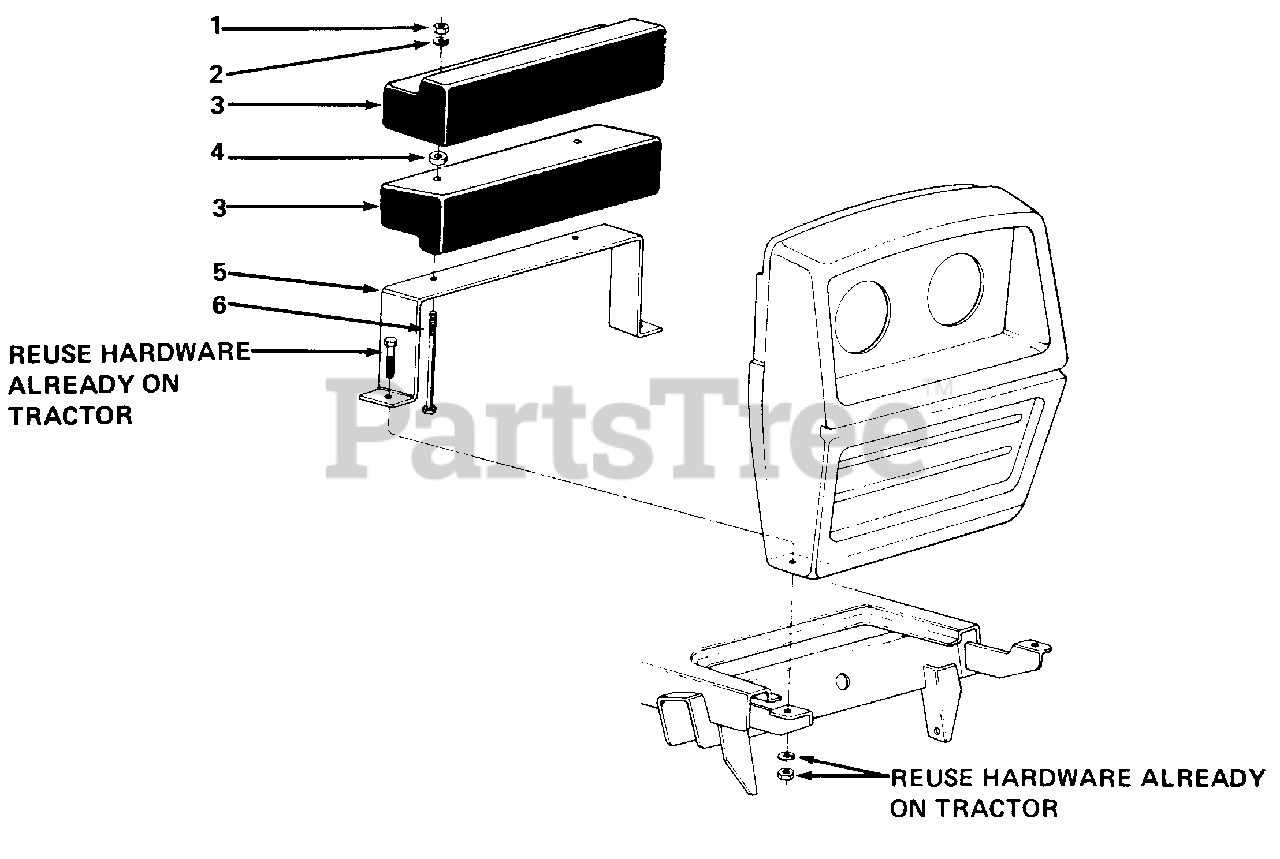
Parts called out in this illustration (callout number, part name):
1	Hex Nut 3/8-16 Thd.*
2	L.-Wash. 3/8 I.D.*
3	Weight-35 lb.
4	Spacer
5	Front Weight Bracket
6	Hex Bolt 3/8-16 x 6.5" Lg.
